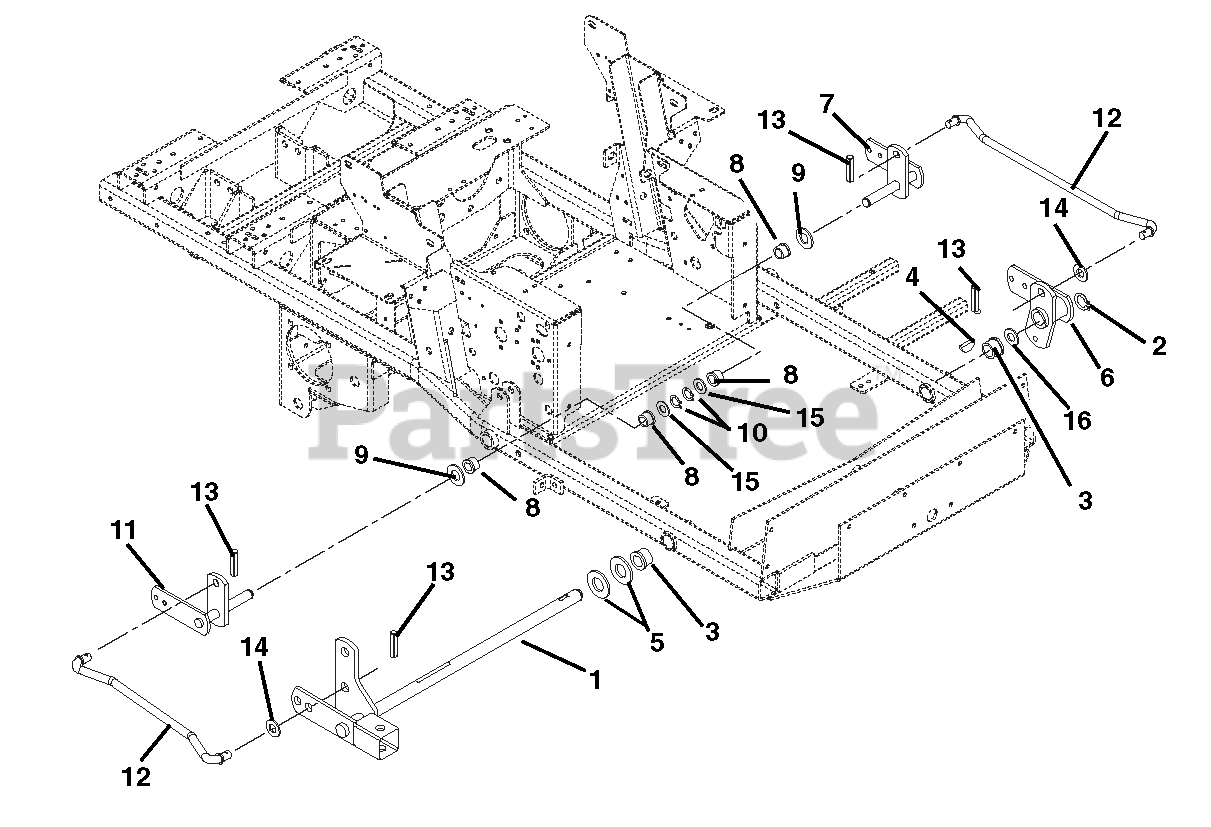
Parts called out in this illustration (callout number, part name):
1	WMT, FRONT MOWER LIFT (HYD)
2	RG-RTNG-EXT 1.00X.078
3	BSHG,1.00ID X 1.125OD X 1.50LG
4	KEY-WDRF .25X1.00 HRD #15
5	WSHR-FL-STL- 1.062X2.0X.134 YZ
6	WMT, LH FRONT MOWER LIFT
7	WMT-LH REAR LIFT ARM (DIESEL)
8	BSHG-FLG .762X1.0X.580X1.48 NY
9	WSHR-HDND-THRST .758X1.23X.031
10	RG-RTNG-EXT .689X.078
11	WMT-RH REAR LIFT ARM (DIESEL)
12	ROD-LIFT ASSIST 19.35"
13	PIN-ROLL .250X1.25 STNLESS STL
14	WSHR-FL-STL .630X1.250X.062 YZ
15	WSHR-FL-STL .755X1.25X.125 YZ
16	WSHR-HDND-THRUST 1.00X1.55X.03
